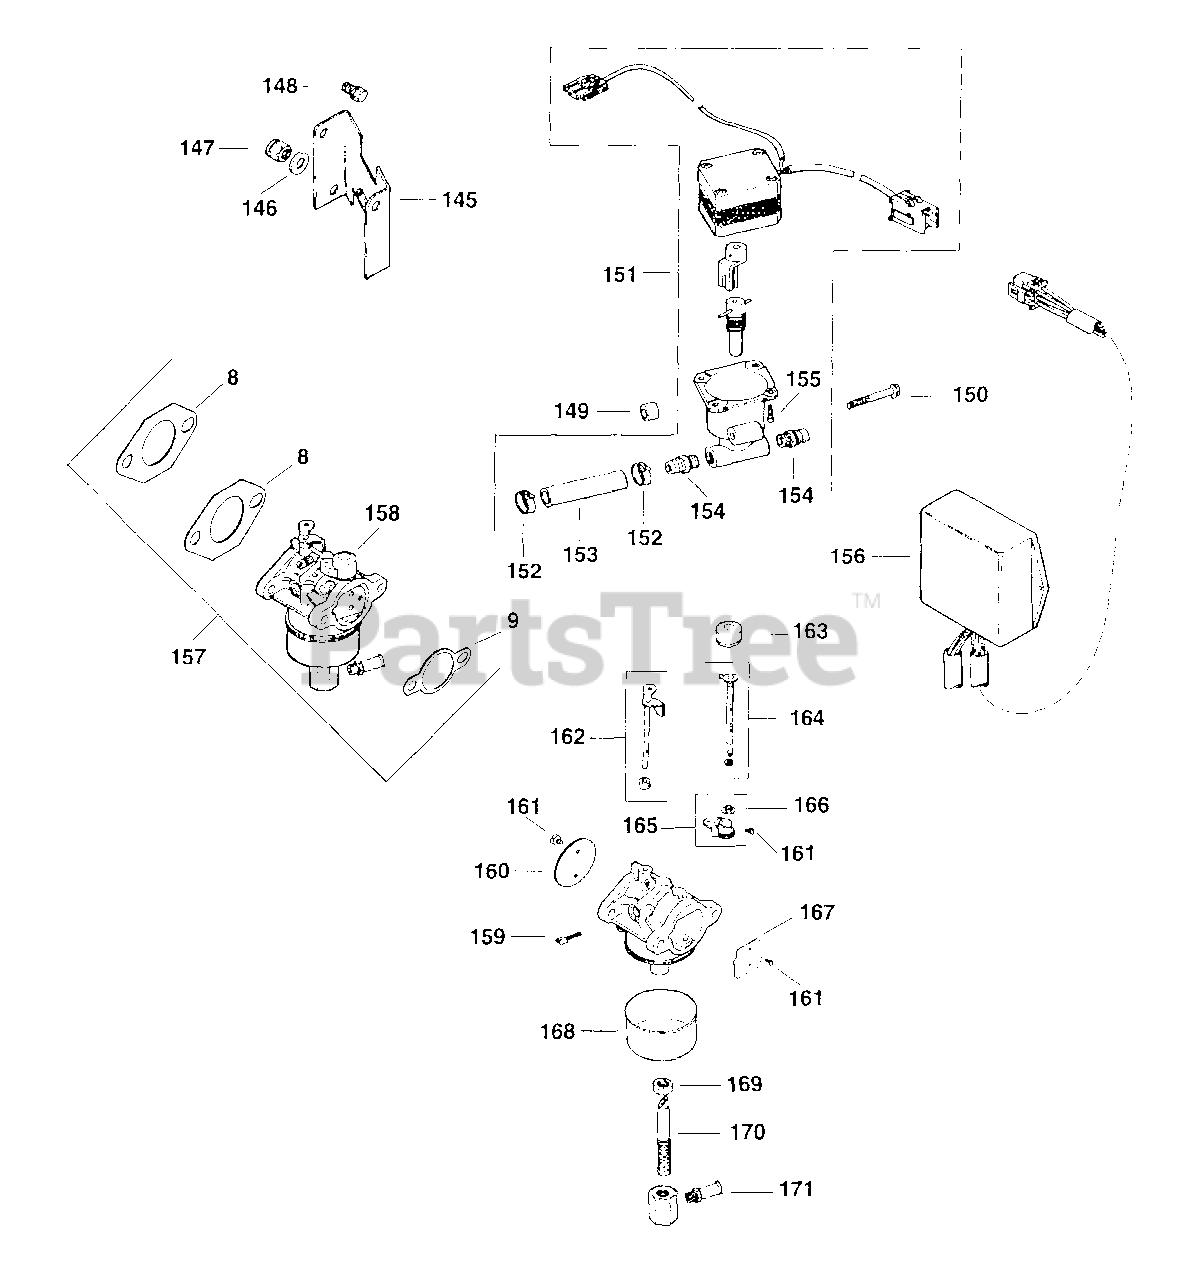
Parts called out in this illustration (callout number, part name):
8	GASKET, CARBURETOR
9	GASKET, AIR CLEANER BASE
145	BRACKET - DISCONTINUED
146	WASHER, FLAT 1/4" (O.D. 5/8")
147	NUT - USE M-641060
148	SCREW - USE M-545010
150	Screw, hex. flange M6x1.0x45
151	VALVE, FUEL METERING
152	CLAMP, HOSE 1/2" USE 25 237 14-S
153	LINE, FLEXIBLE FUEL - DISC.
154	FITTING, BARBED - USE 25 294 16-S
155	SCREW, HEX SOCKET HEAD - DISCONTINUED
156	CONTROL - USE 12 526 02
157	KIT, CARBURETOR W/GASKET LPG - DISC.
161	SCREW, VALVE
162	SHAFT, THROTTLE
163	CAP, CHOKE LEVER
164	SHAFT, CHOKE
165	KIT, CHOKE LEVER REPAIR - USE 12 757 32-S
166	BUSHING, CHOKE
167	PLATE, CHOKE
169	NUT, 3/8-24 JAM, GRADE 2 - DISC.
170	VALVE, METERING - DISCONTINUED
171	FITTING, HOSE TO PIPE
